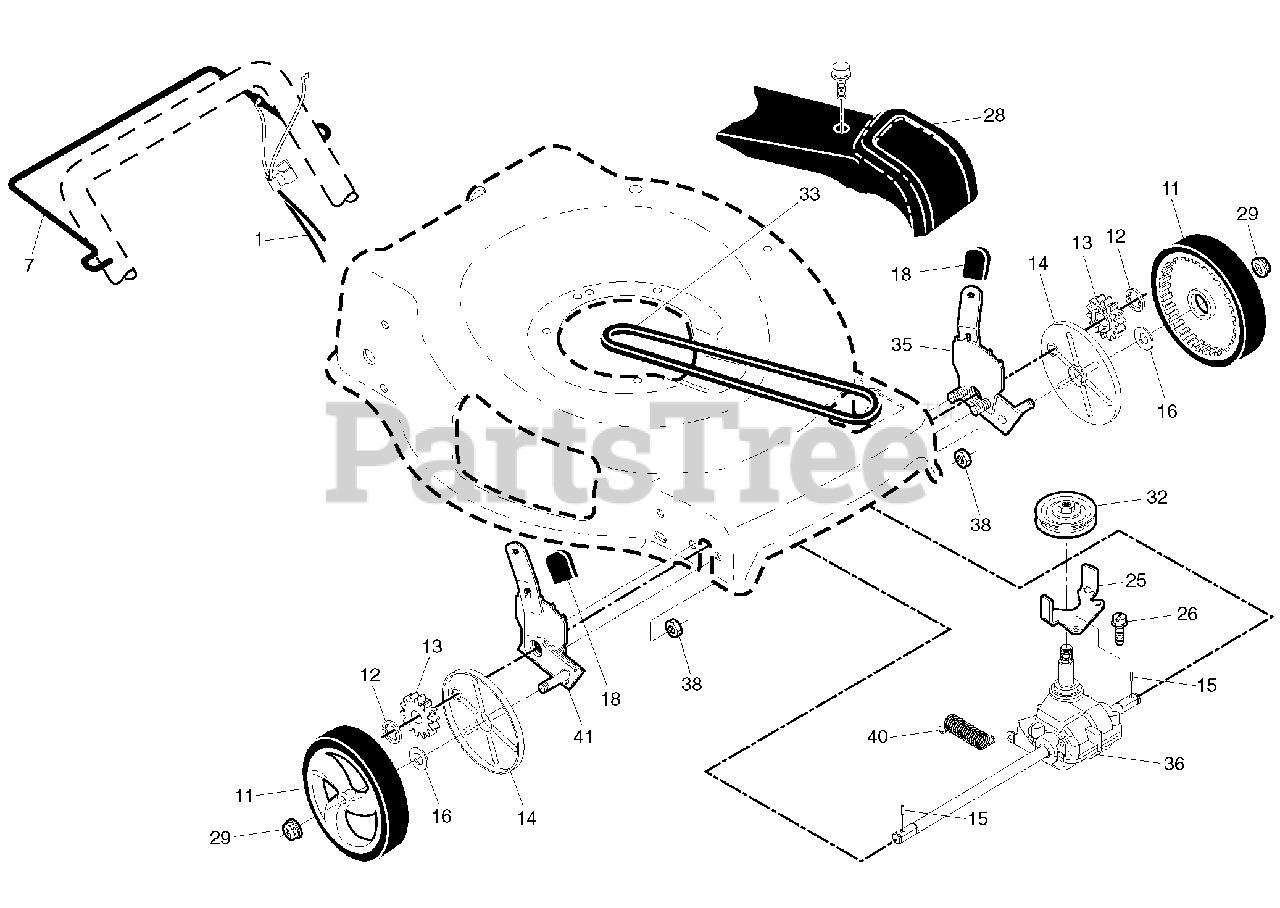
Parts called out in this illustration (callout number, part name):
1	CABLE.DRIVE.VS/SS.22+FGD.MCCUL
7	BAIL.DRIVE.SS.CURVED.BLK.428
12	E-RING 7/16 RE
13	PINION.14.TEETH.FGD
14	Inner Wheel Dust Cover
15	PAWL, DRIVE
16	WASHER FLUT
18	SELECTOR KNOB
25	BRACKET.BELT.GUIDE.22+FGD.BZP
28	Drive Cover Assembly, 419930 Ce
29	NUT.HEX.FLANGE.3/8-16.LOCKNUT
32	PULLEY.DRIVEN.EZ/VARI (2 2MC)
33	BELT.DRIVE.FGD.
35	Adjuster Assembly Kit, LH Front
38	NUT.FLANGE.1-4-20-SERR
41	Adjuster Assembly Kit, RH Front
